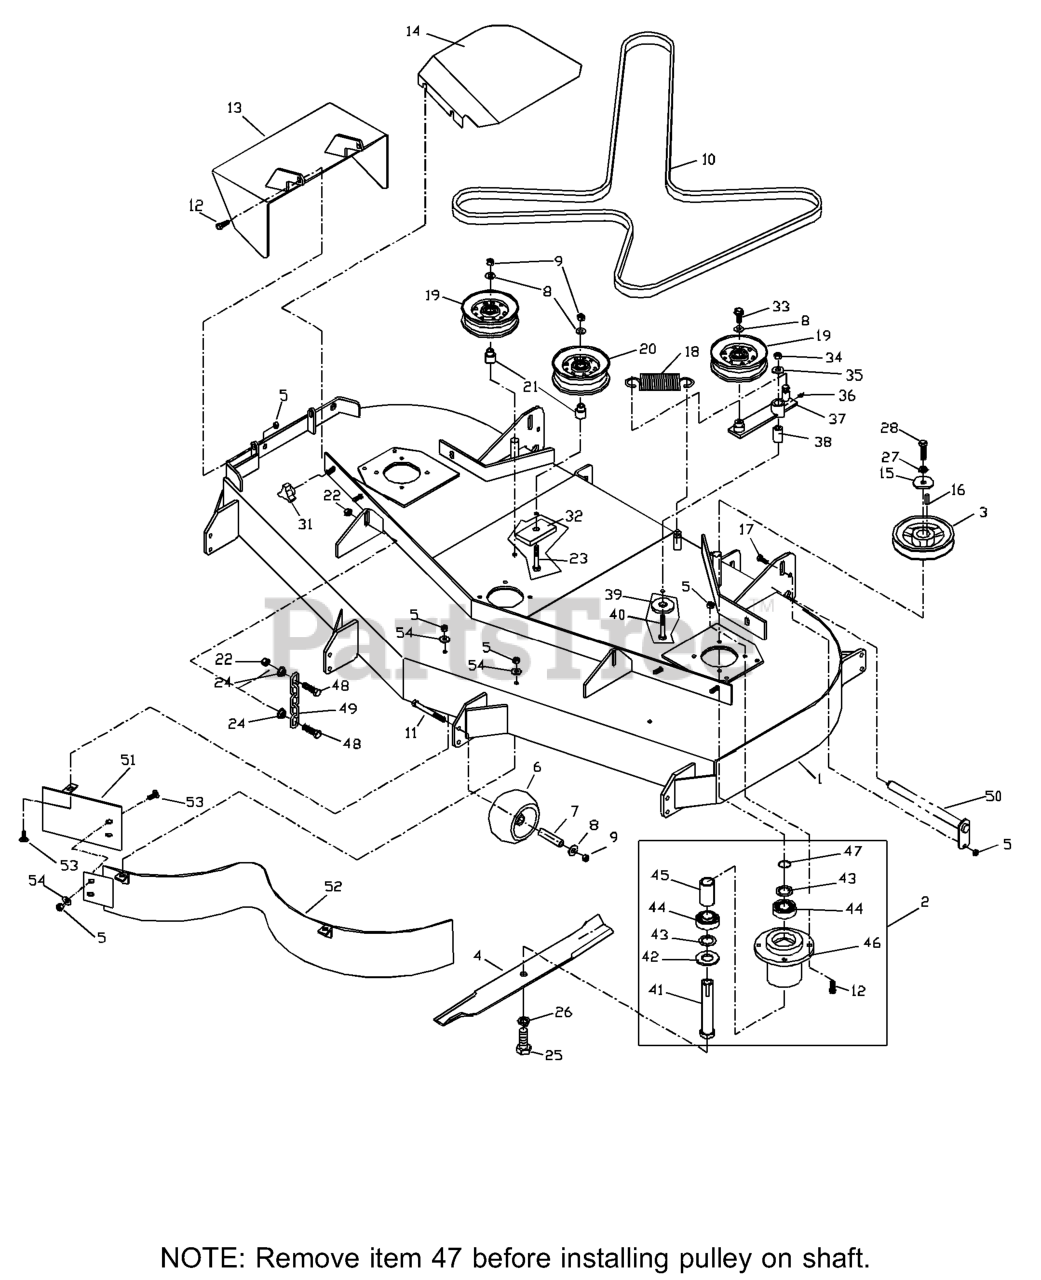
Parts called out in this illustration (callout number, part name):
1	DECK W/DECALS 61" HUS
2	HOUSING ASM.
4	BLADE OEM 21" (61" DECK)
5	NUT 5/16C CENTERLOCK
6	ANTI-SCALP ROLLER
8	WASHER 3/8 FLAT
9	NUT 3/8C CENTERBLOCK
10	DECK BELT 61
11	HCS 3/8C X 3 1/2
12	HCS 5/16C X 1
13	DISCHARGE CHUTE
14	61 B.S.PAINTED, RT
14	61 B.S.PAINTED, LT ORANGE
15	SPINDLE WASHER
16	KEY 1/4 SQ X 1 1/8
17	HCS 5/16C X 3/4
18	DECK SPRING
19	IDLER PULLEY
20	IDLER PULLEY (TALL)
21	IDLER BUSHING
22	NUT 7/16C CENTERLOCK
23	HCS 3/8C X 2 1/2
24	NUT 7/16C WHIZ
25	HCS 5/8F X 1 1/4
26	LOCKWASHER 5/8
27	WASHER 7/16 LOCK
28	HCS 7/16F X 1 1/2
31	KNOB, THREE PRONG
32	SUPPORT PLATE
33	4CS 3/8C X 1 SERRATED HEAD
34	NUT 1/2-13 HEX NYLOC ZD
35	WASHER 1/2 FLAT
36	ZERK
38	PIVOT BUSHING
39	WASHER, SUPPORT
40	HCS 1/2C X 3 1/4
42	MACHINERY BUSHING 10 GA.
43	BUSHING.MACHINE.18.GAUGE
44	BEARING
46	HOUSING, DIE CAST
48	HCS 7/16C X 1 1/2
49	LIFT CHAIN
51	CENTER BAFFLE - 61
52	MAIN BAFFLE - 61" BLK
53	CARRIAGE BOLT 5/16C X 5/8"
54	WASHER 5/16 FLAT
